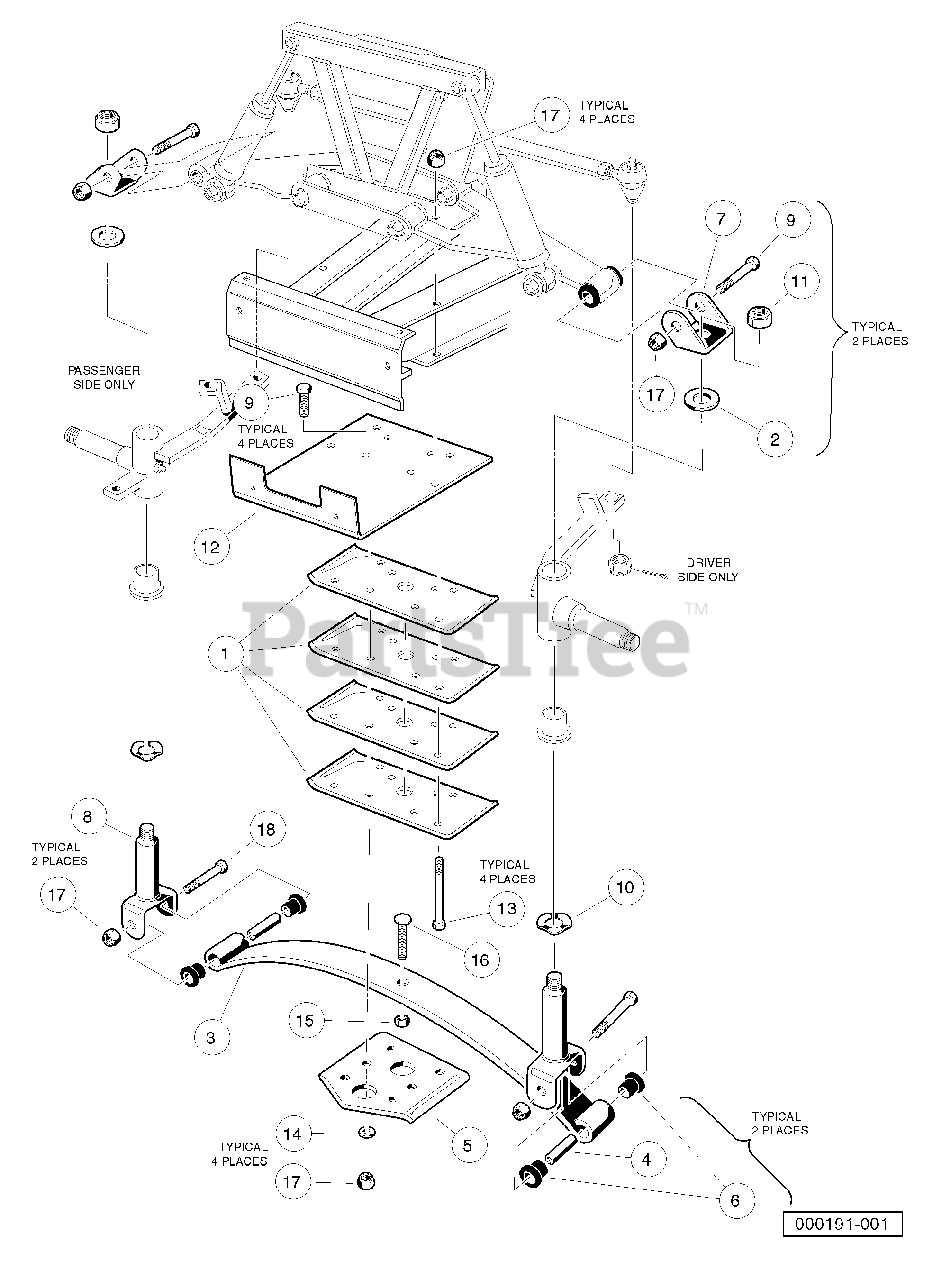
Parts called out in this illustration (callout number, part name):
1	Plate, Spring Mount
2	Bearing, Thrust
3	Spring, Front Leaf
4	Bushing, Steel
5	Plate, Front Spring Retainer
6	Bushing, Urethane
7	Clevis, Delta Upper
8	King Pin Assembly
9	Screw, 3/8-16 X 2.75 Hx Hd Cap
10	Washer, 1.125 Od Wave
11	Locknut, 1/2-20 Nylon Insert
12	Support, Brush Guard
13	Screw, 3/8-16 X 5.50 Hx Hd Cap
14	Washer, Lock, Hel Sp 3/8 Reg
15	Nut, Hex 3/8-16
16	Screw, Eccentric Adjustment
17	Locknut, 3/8-16 Hex
18	Screw, 3/8-16 X 3.375 Hex Cap
